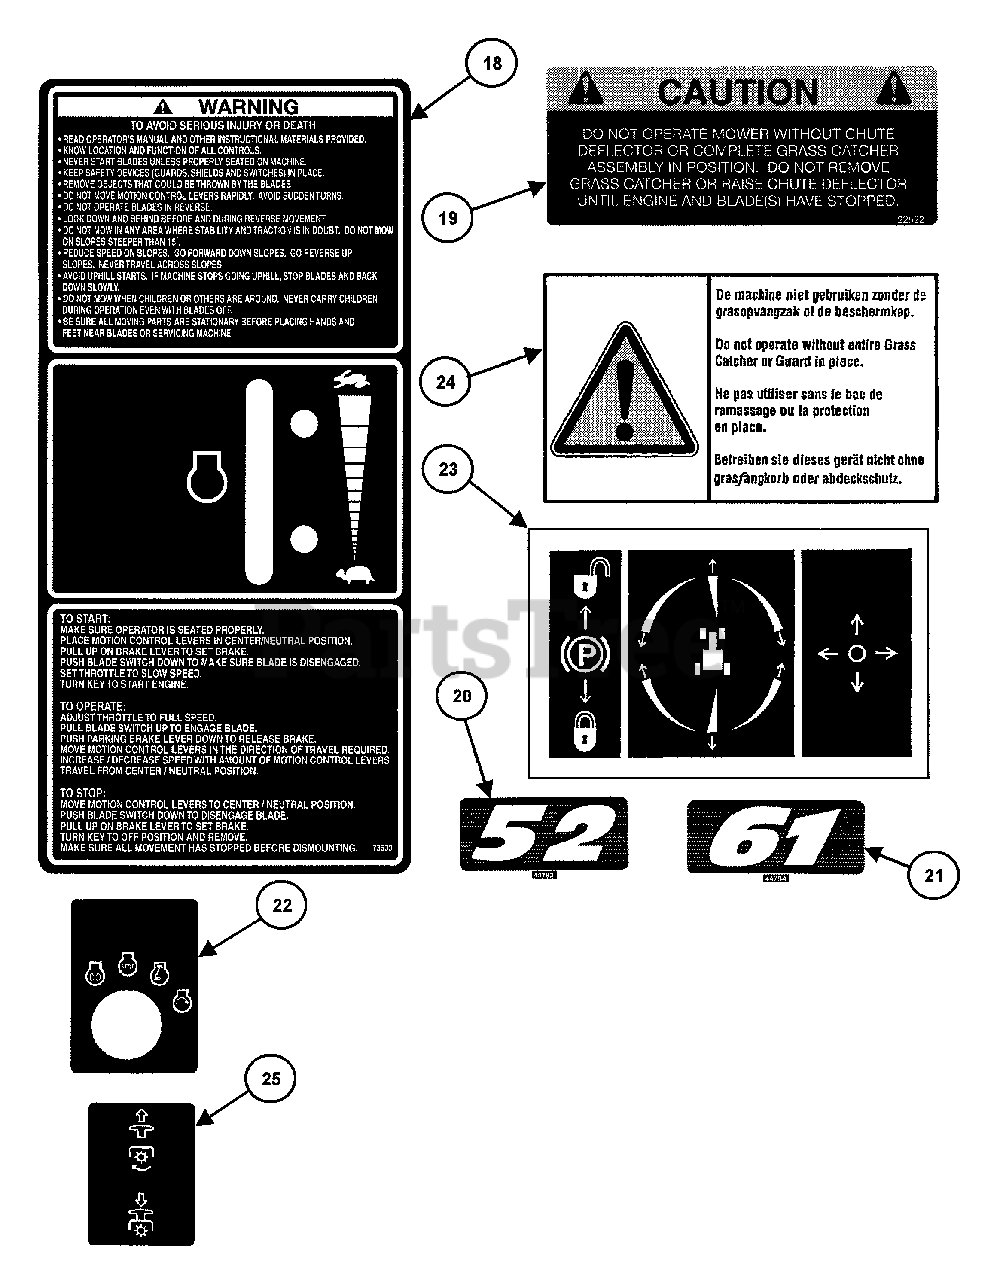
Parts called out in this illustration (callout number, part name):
18	DECAL, Throttle
19	DECAL, Caution
20	DECAL, Deck Size 52"
21	DECAL, Deck Size 61"
22	DECAL, Key Switch
23	DECAL, Joystick Operation
24	DECAL, Warning 4 Language
25	DECAL, PTO Switch
